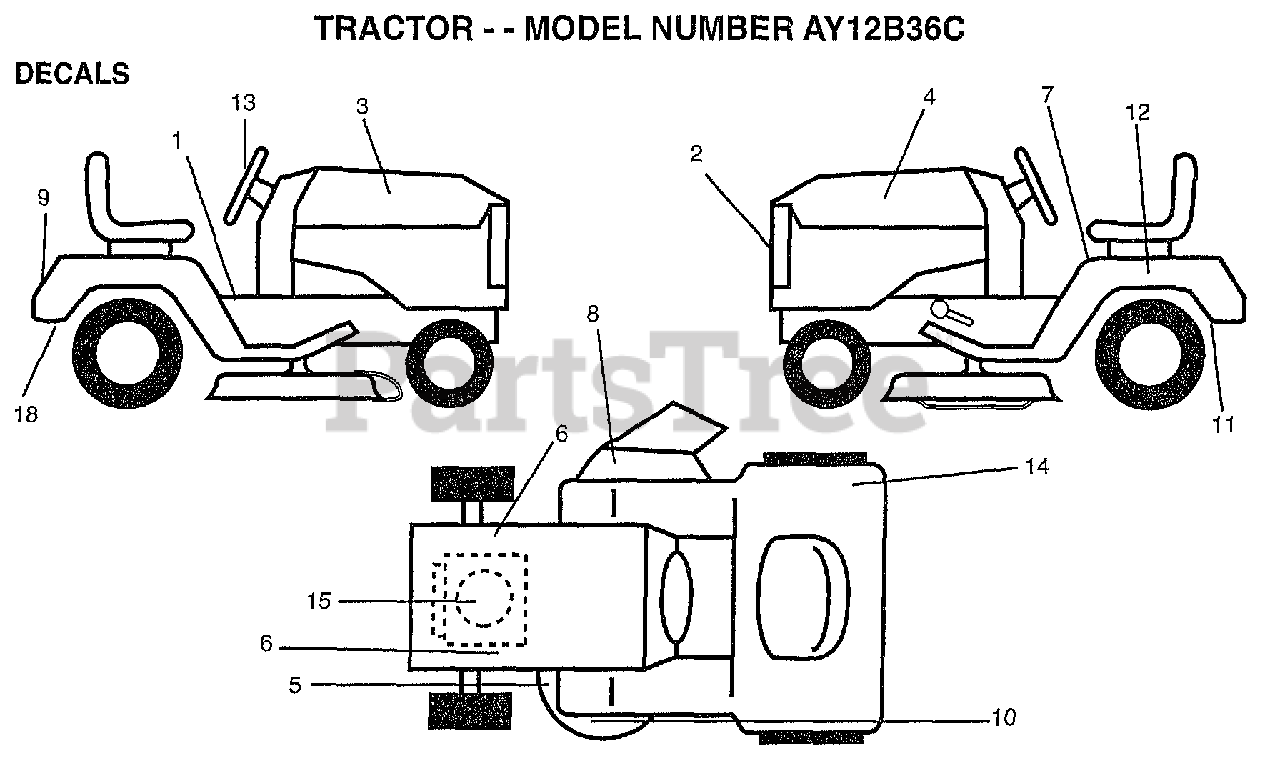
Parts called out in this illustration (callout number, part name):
1	DECAL CLUTCH/BRAK
2	"DECAL,LIGHT BOX"
3	DECAL.HOOD.RH
4	DECAL.HOOD.LH
5	DECAL.V.BELT
6	"DECAL CHASSIS,HOT"
7	DECAL.READ.O.MANU
8	DECAL.DANGER.CUTF
9	DECAL.FENDER
10	DECAL DECK WIZ +
11	DECAL.DRAWBAR.LDL
12	DECAL.BATRY.3-3908
13	DECAL.INSERT.STR
18	DECAL.EURO.ST.CE.
